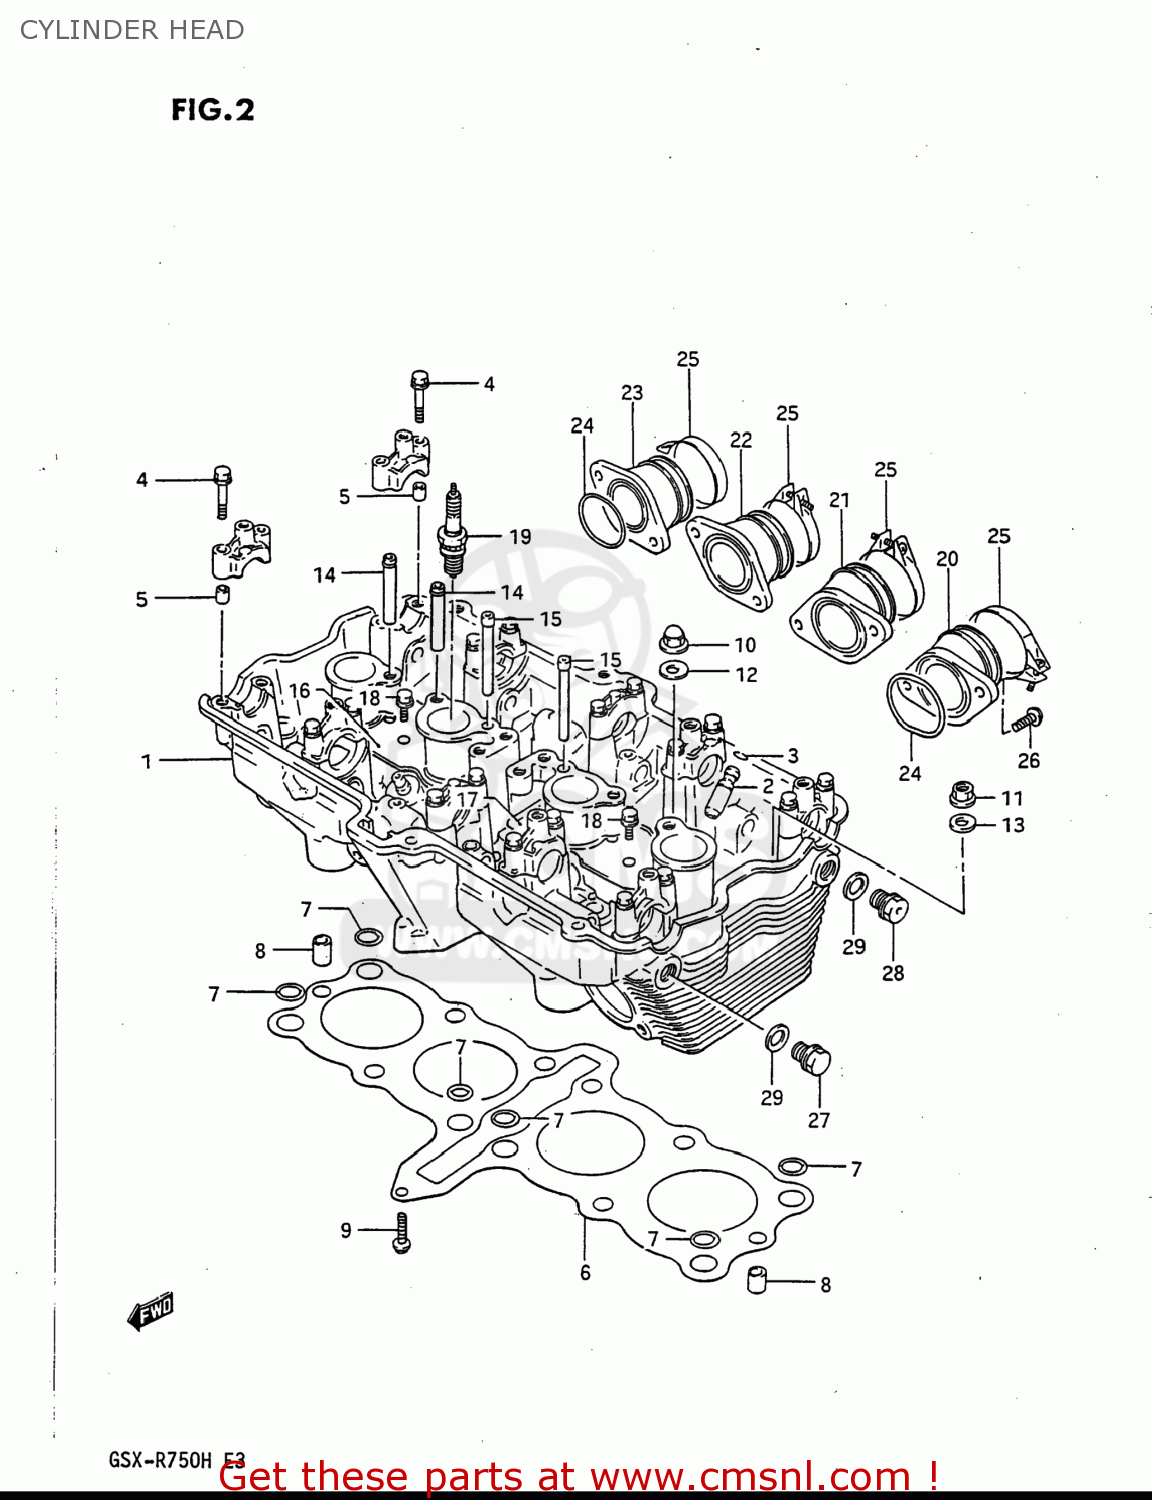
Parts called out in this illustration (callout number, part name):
1	HEAD ASSEMBLY,CYLINDER
2	GUIDE,VALVE
3	RING,SNAP
4	BOLT(6X39)
5	PIN(6.2X8X11)
6	GASKET,CYLINDER HEAD (NAS)
7	O RING(D:2.6,ID:12.1)
8	PIN
9	BOLT
10	NUT
11	NUT
12	GASKET(10.2X20X2).3 (NAS)
13	WASHER (10.5X22X2.3)
14	PIPE,OIL NO.1
15	PIPE,OIL NO.3
16	PLATE,OIL PIPE,R
17	PLATE,OIL PIPE,L
18	BOLT
19	SPARK PLUG D9EA
20	PIPE,INTAKE
21	PIPE,INTAKE
22	NET,INTAKE
23	PIPE,INTAKE
24	O RING(D:2.4,ID:39.7)
25	CLAMP
26	SCREW
27	PLUG
28	PLUG
29	GASKET(14X19.2X2) (NAS)
